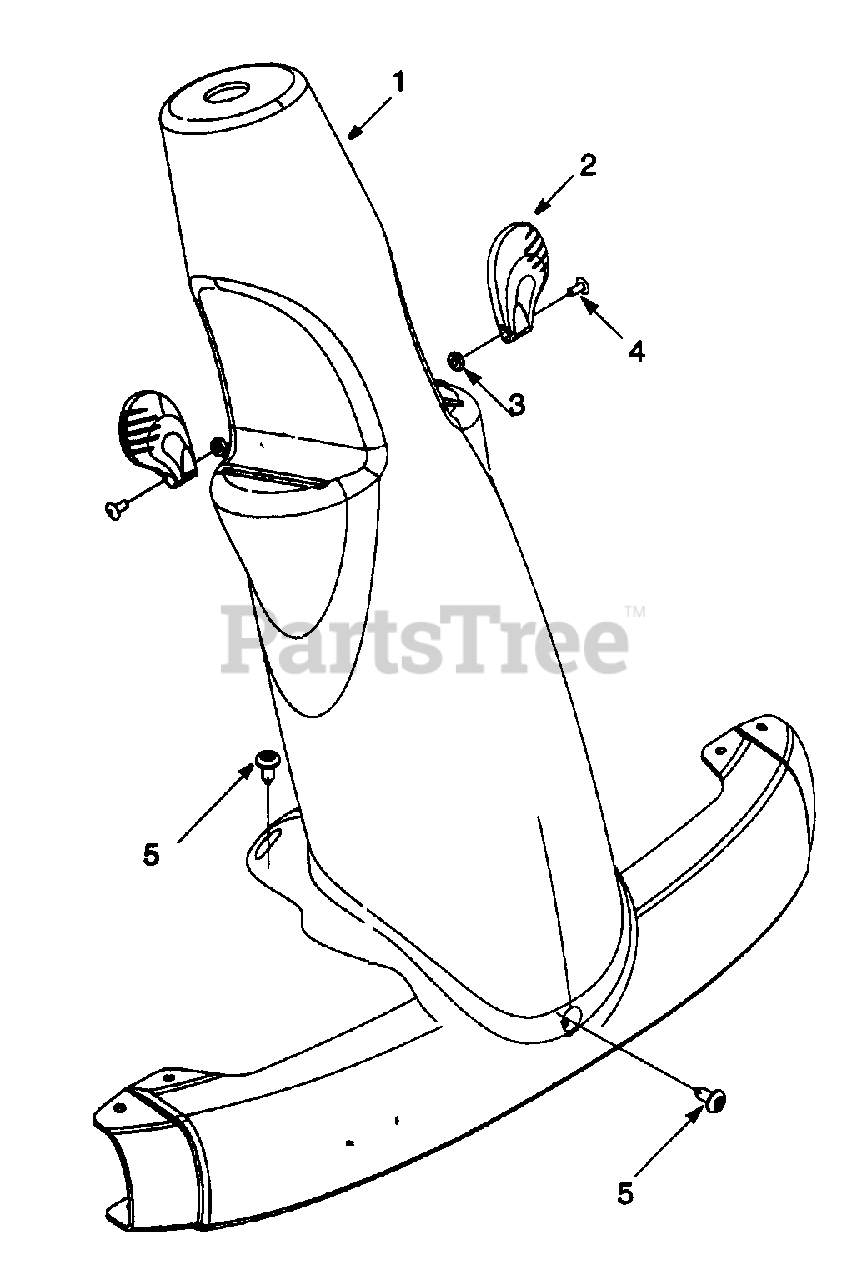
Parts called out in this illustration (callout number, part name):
1	Steering Column: Green
2	Control Knob: Yellow
3	Hex Nut 8-32
4	Pan Head Machine Screw #8-32
5	Hex Screw TT 1/4-20 x .50"
